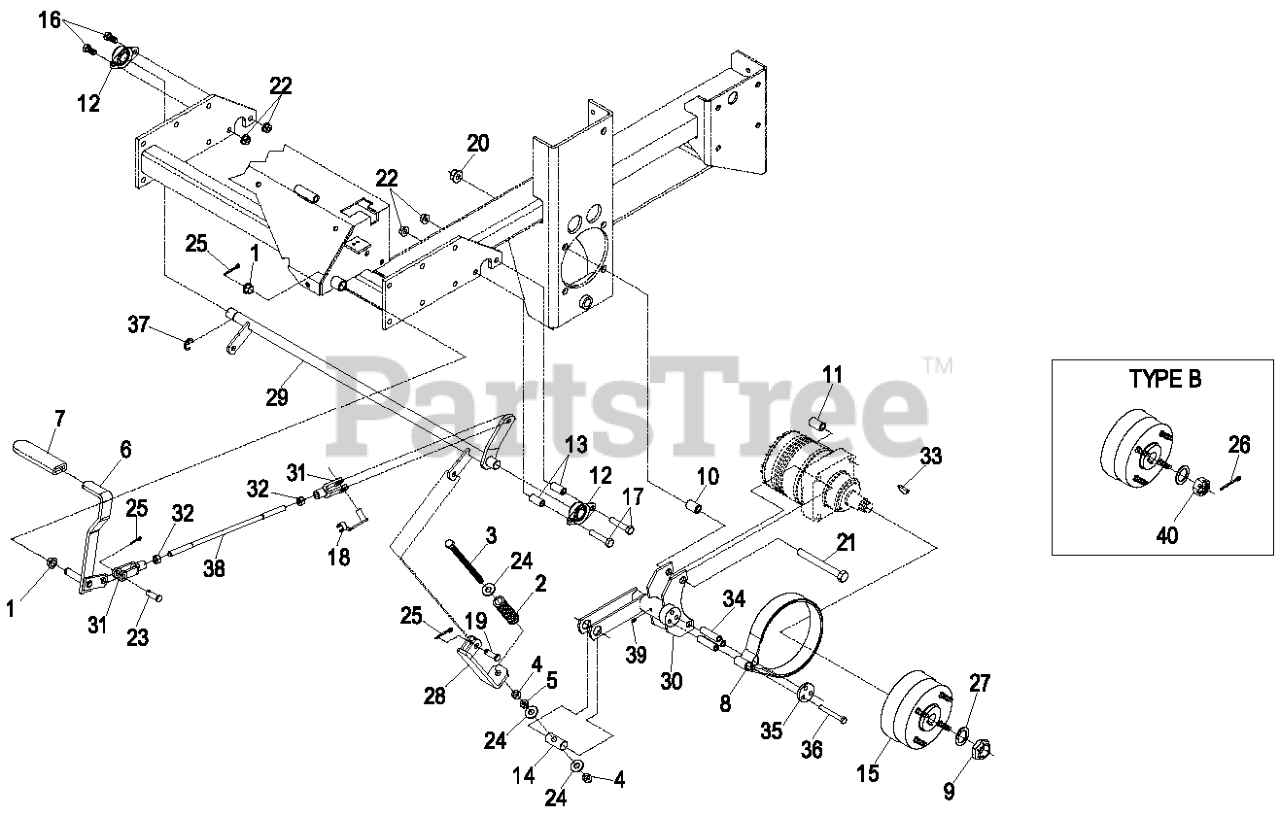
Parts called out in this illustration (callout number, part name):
1	BEARING-CONTROL
2	SPRING-COMPRESSION
3	BOLT-TAP, HH
4	NUT-LOCK, NI
5	NUT-JAM
6	BRAKE LEVER AND GRIP ASM
7	GRIP-LEVER
8	BAND,BRAKE
9	LOCKNUT
10	SPACER-WHEEL, SHORT
11	SPACER-WHEEL, LONG
12	BEARING-FLANGE, SIDE
13	SPACER-RETAINER, BRAKE
14	PIN-TRUNION
15	HUB W/STUDS ASM
16	SCREW-HH
17	SCREW-HH
18	PIN-SPRING, CLEVIS
19	PIN-CLEVIS
20	NUT-HHF
21	SCREW-HH
22	NUT-HHF, WHIZ
23	PIN-CLEVIS
24	WASHER-FLAT
25	PIN-COTTER
26	PIN-COTTER
27	WASHER-SPACER
28	LINKAGE-BRAKE, LOWER
29	SHAFT-BRAKE
30	BRAKE-NARROW
31	YOKE-LINKAGE, BRAKE
32	NUT-HEX
33	KEY-WOODRUFF
35	RETAINER-BAND, BRAKE
36	SCREW-HH
38	ROD-BRAKE
39	FITTING-GREASE
